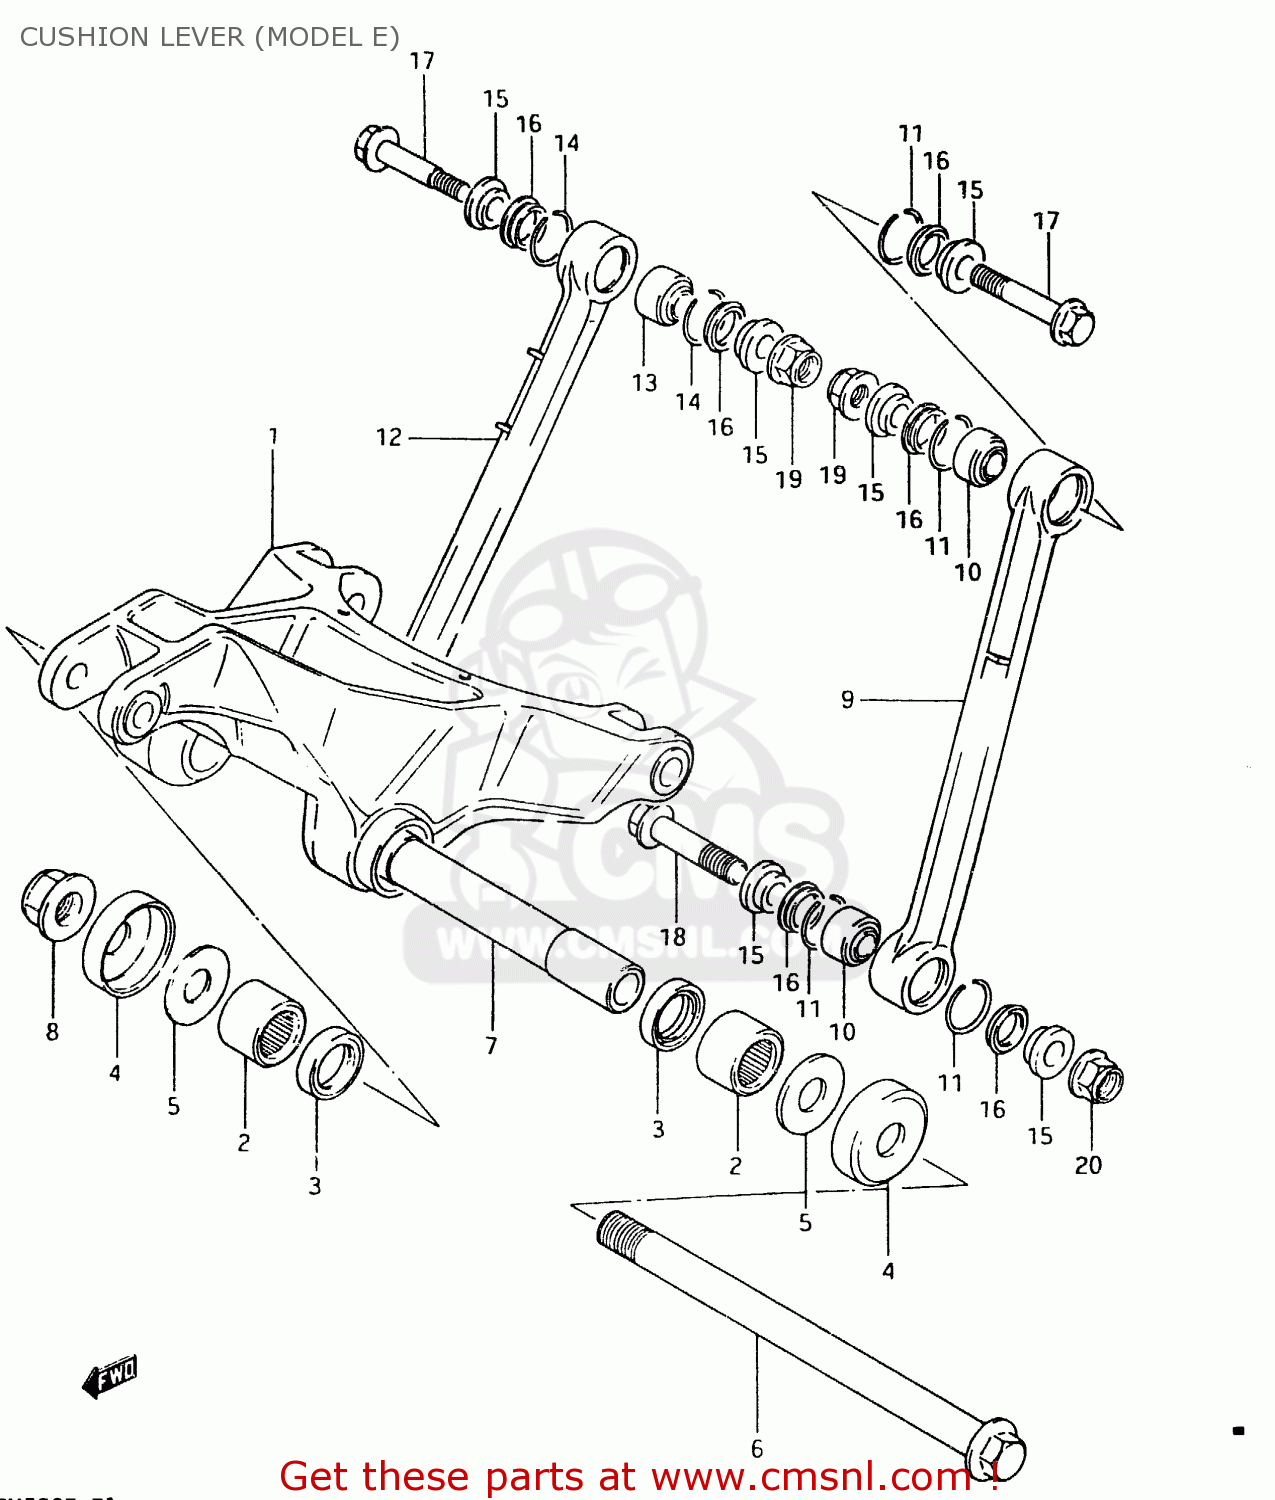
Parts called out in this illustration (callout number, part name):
1	LEVER SET,REAR CUSHION
2	BEARING(20X27X25)
3	SEAL,CUSHION LEVER DUST
4	CVR,RR SWGARM DUST SEAL(OD:40)
5	WASHER
6	SHAFT,REAR CUSHION LEVER
7	SPACER,REAR CUSHION LEVER
8	NUT
9	LEVER SET,REAR CUSHION
10	BEARING(10X21X13)
11	RING,BEARING STOPPER
12	LEVER SET,REAR CUSHION
13	BEARING(10X21X13)
14	RING,BEARING STOPPER
15	SPACER,REAR CUSHION ROD
16	SEAL,RR CUSHION ROD DUST
17	BOLT,REAR CUSHION ROD
18	BOLT,RR CUSHION ROD LWR
19	NUT
20	NUT
